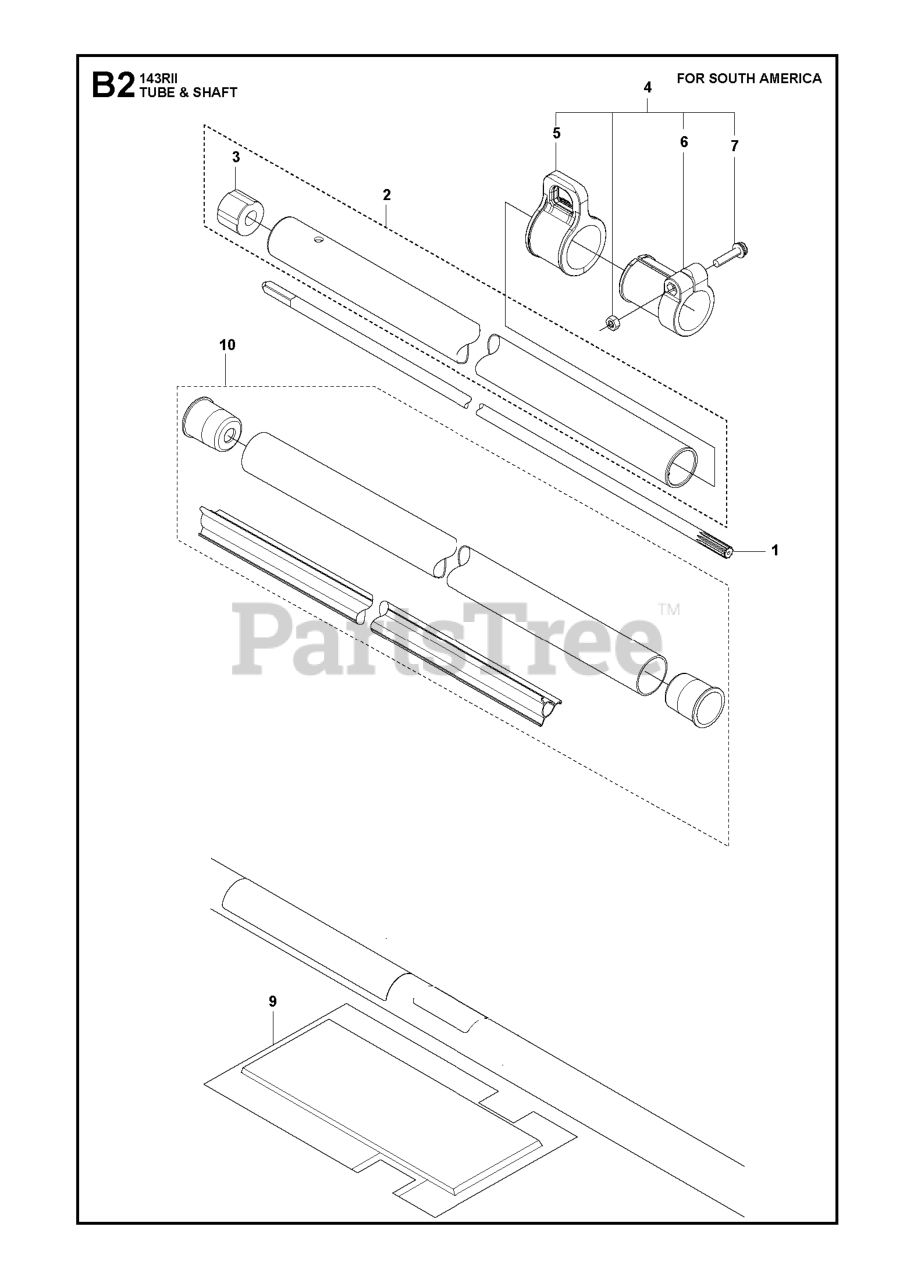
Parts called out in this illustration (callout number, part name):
1	DRIVE SHAFT
2	PIPE COMP.
9	PROTECTOR (RPLS 405017110)
